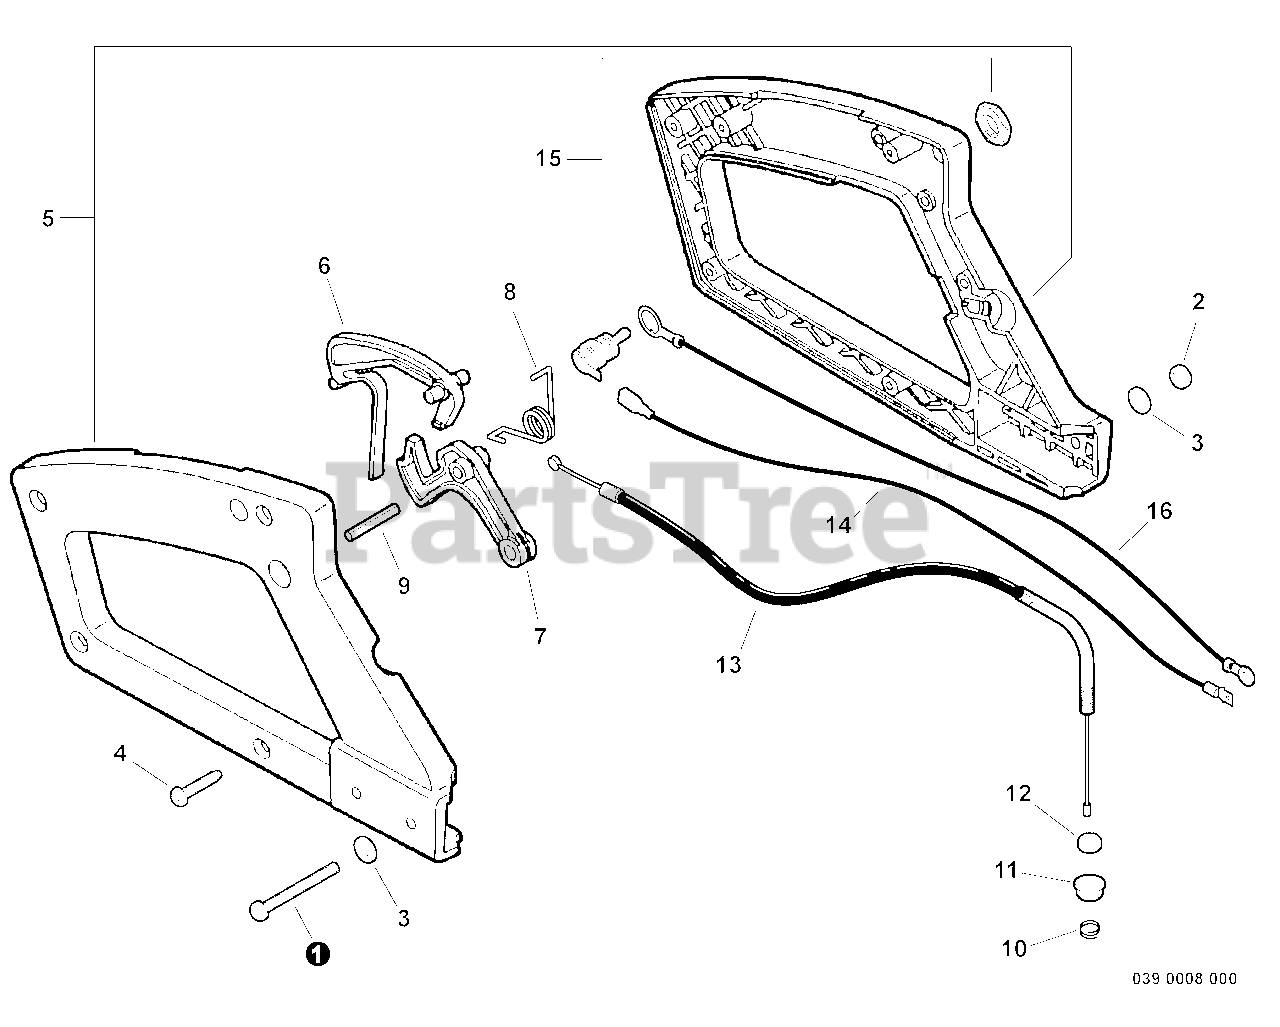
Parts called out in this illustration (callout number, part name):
1	SCREW - 5X40
2	LOCKNUT - 5
3	WASHER - 5
4	SCREW - 4X16
5	HANDLE ASSY - REAR
6	LOCKOUT, THROTTLE
7	TRIGGER, THROTTLE
8	SPRING, TRIGGER
9	PIN - SPRING -- 5X25
11	NUT - 6 -- FLANGE
13	CABLE, THROTTLE
14	LEAD - IGNITION
15	IGNITION SWITCH ASSY
16	LEAD - GROUND
